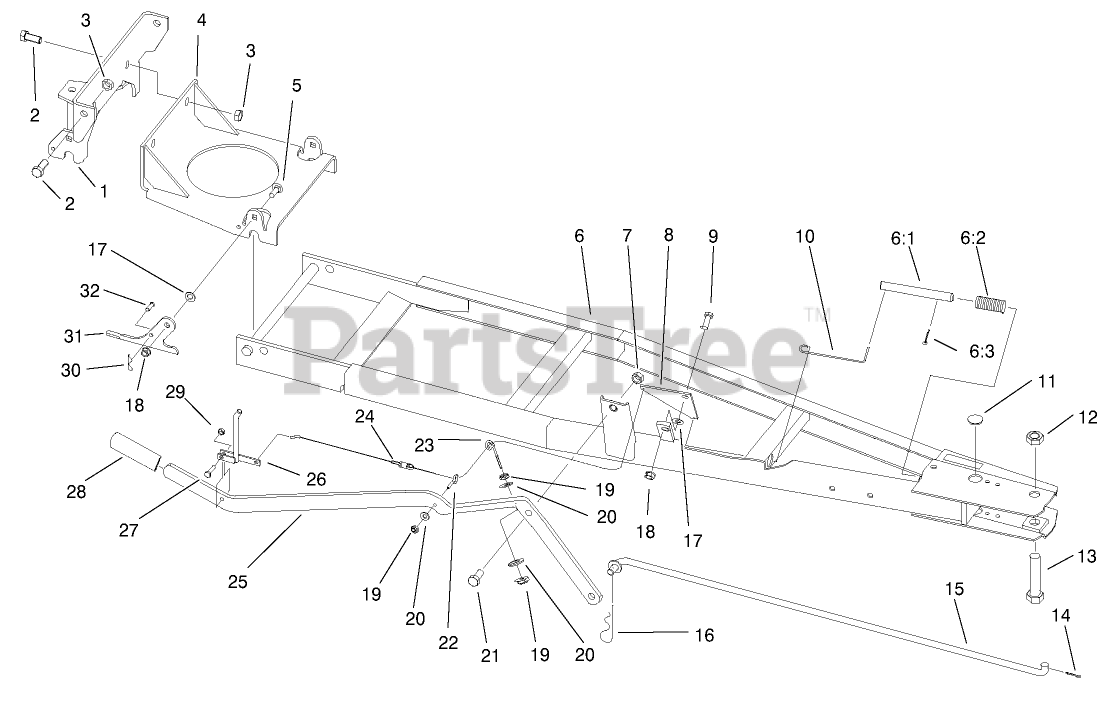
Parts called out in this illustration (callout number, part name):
1	BRACKET-MOUNTING
2	SCREW-HH
3	NUT-LOCK, NI
4	BRACKET-BLADE MOUNT ASM
5	BOLT-CARR
6:1	PIN-INDEX
6:2	SPRING-COMPRESSION
6:3	PIN-COTTER
7	NUT-JAM
8	PLATE - INDEX
9	SCREW-HH
10	ROD-LOWER INDEX
11	PLUG
13	SCREW-HH
14	PIN-COTTER
16	PIN-HAIR
17	WASHER-FLAT
18	NUT-LOCK, NI
19	NUT-LOCK, NI
20	WASHER-FLAT
21	SCREW-HH
22	EYEBOLT
24	CABLE ASM - LIFT
25	LEVER - INDEX BLADE
26	LEVER-INDEX
27	SCREW-HH
28	GRIP
30	PIN-HAIR
31	PLATE-LATCHING
32	PIN-CLEVIS
